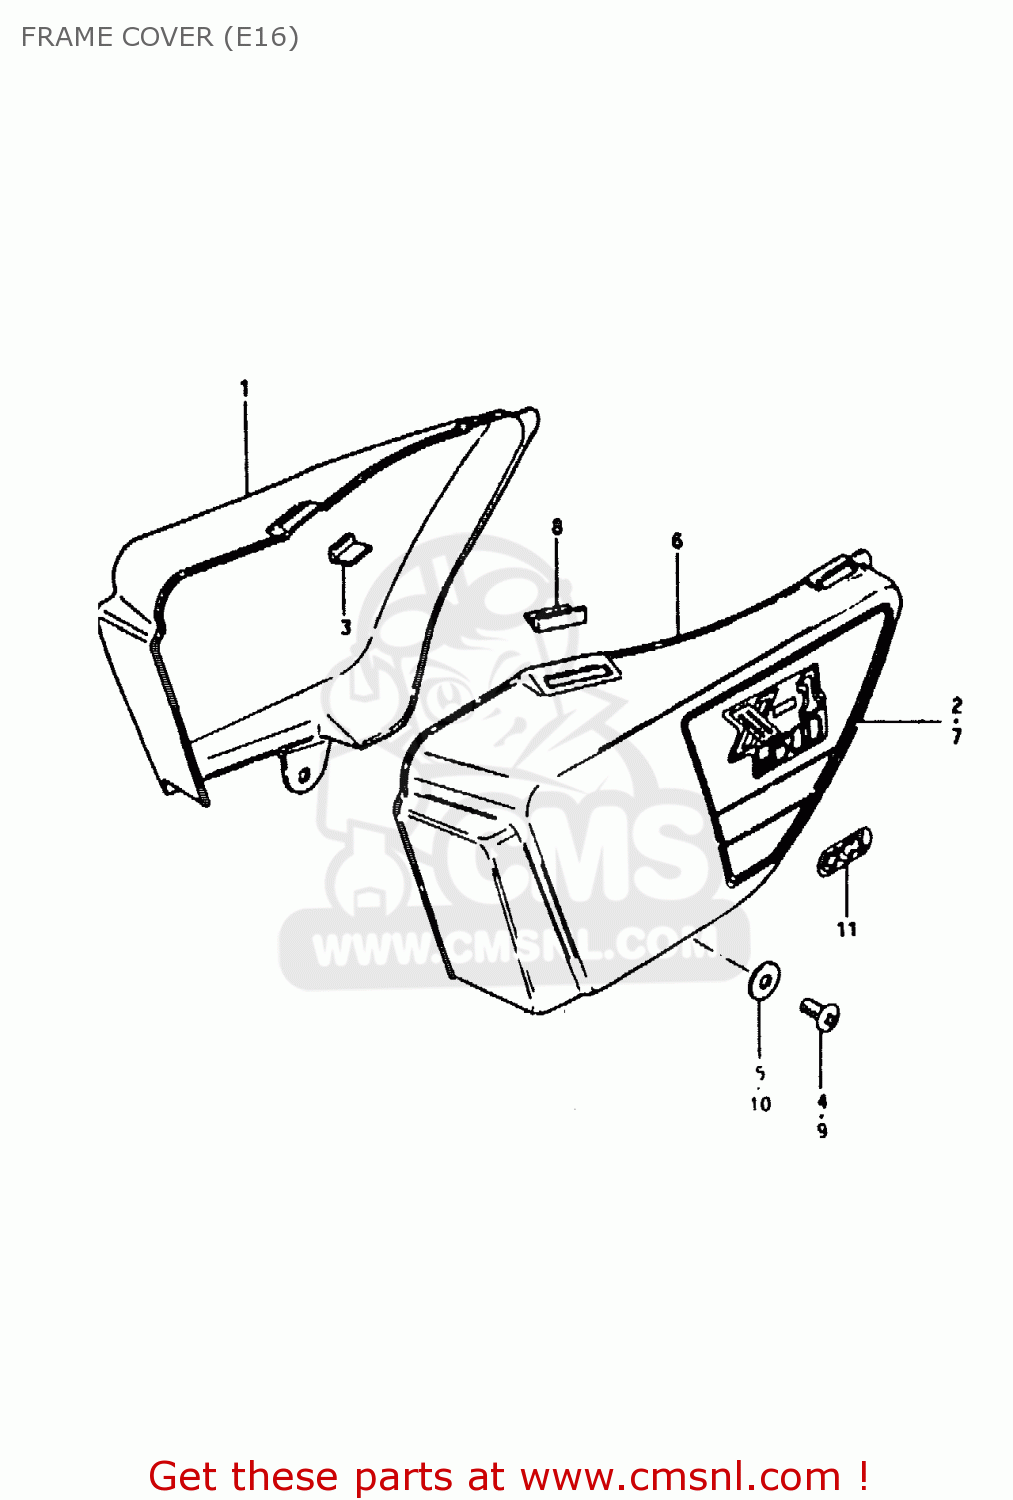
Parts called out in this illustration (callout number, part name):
1	COVER, FRAME RH (BLACK)
2	EMBLEM, RH
3	CUSHION,FRAME COVER
4	SCREW
5	WASHER
6	COVER, FRAME LH (BLACK)
7	EMBLEM, LH
8	CUSHION,FRAME COVER
9	SCREW
10	WASHER
11	EMBLEM,CCIS
